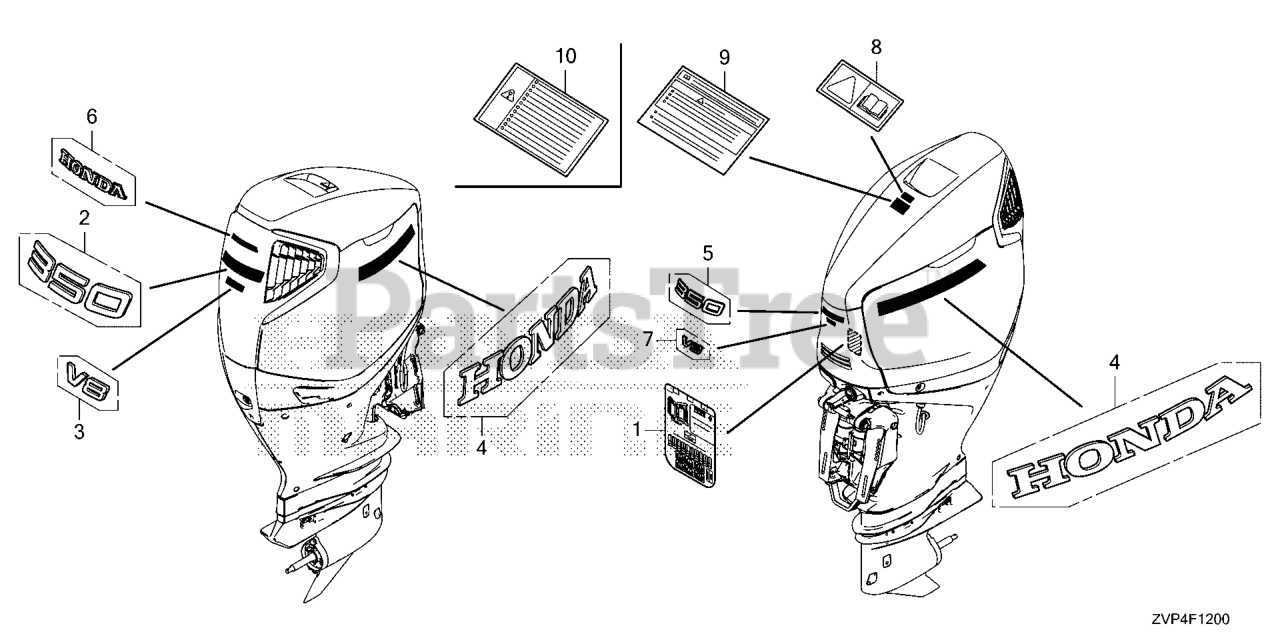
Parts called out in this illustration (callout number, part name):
2	EMBLEM (350) *CHPL*
3	EMB, RR. (V8) *CHPL*
4	SIDE EMBLEM *CHPL*
5	EMBLEM (350) *CHPL*
6	EMBLEM, HONDA *CHPL*
7	EMB, FR. (V8) *CHPL*
9	LABEL, WARNING OPERATOR (ENGLISH)
